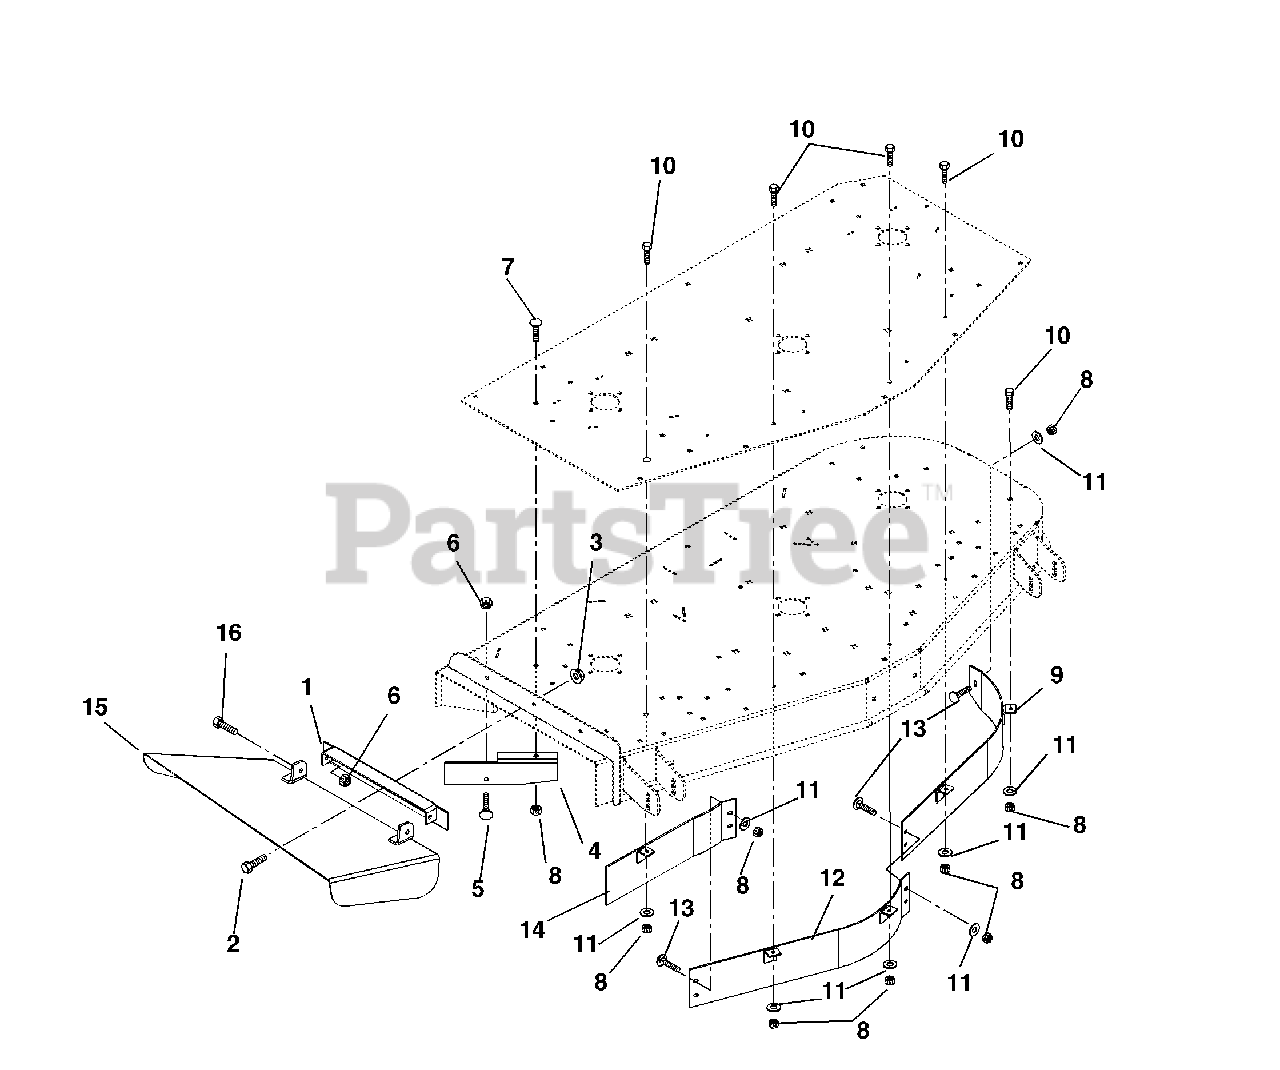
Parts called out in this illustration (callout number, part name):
1	Weldment, Discharge Chute Bracket
2	Bolt-Hex .38-16 x 1.00 Grade 5
3	Nut-Locking-Flange .38-16
4	Deflector, 60
5	Bolt-Round Head Square Neck .38-16 x 1.00 Grade 2
6	Nut-Locking-Center .38-16
7	Bolt-Round Head Square Neck .31-18 x 1.00 Grade 5
8	Nut-Locking-Nylon .31-18
9	Weldment, 60" Left Hand Baffle-Upper
10	Bolt-Hex .31-18 x 1.00 Grade 5
11	Washer-Flat-Steel .312 x .734 x .065
12	Weldment, 60" Center Baffle-Up
13	Bolt-Round Head Square Neck .31-18 x .75 Grade 5
14	Weldment, 60" Right Hand Baffle-Upper
15	Weldment, Discharge Chute 60"
16	Bolt-Hex .38-16 x 1.00 Grade 5
17	60" Discharge Cover
18	60" Mulch Kit
